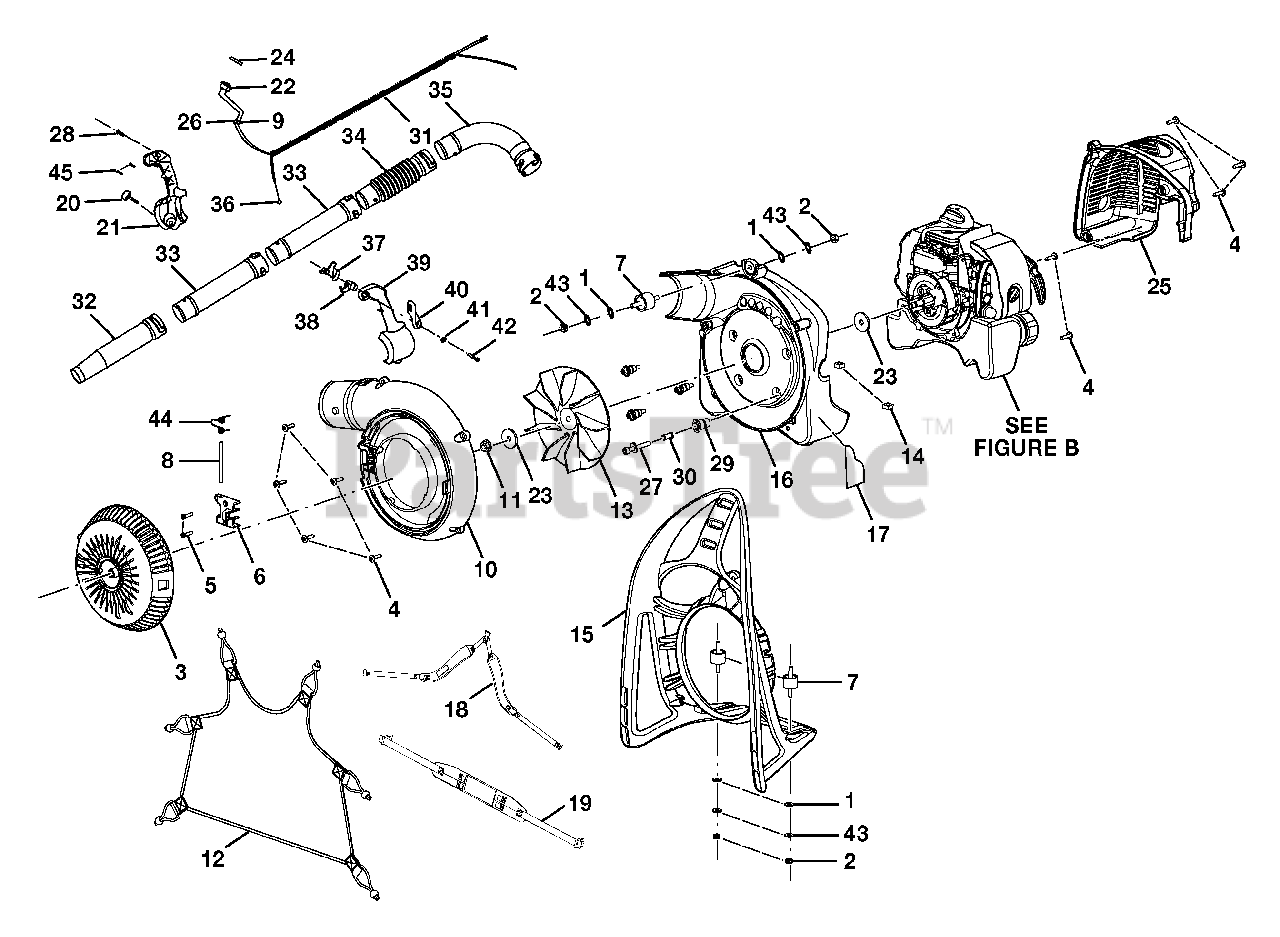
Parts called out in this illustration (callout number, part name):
4	SCREW (#10-14 X 7/8 in.)
5	SCREW (#8-14 x 16.3 mm)
6	VACUUM DOOR HINGE
7	RUBBER AV ISOLATOR
8	HINGE PIN
9	LEAD ASSEMBLY (BLACK)
10	OUTER VOLUTE HOUSING
11	RETAINING WASHER NUT
13	24.5 CC BLOWER FAN
14	SQUARE NUT
16	HOUSING INNER VOLUTE
17	WARNING LABEL
18	SHOULDER STRAPS
19	WAIST STRAP
21	HOUSING-RH
23	FAN SPACER WASHER
24	DUST COVER
25	ENGINE SHROUD HOUSING
26	LEAD ASSEMBLY (RED)
27	SCREW (M5 X 0.8 CAP HD.)
28	SCREW (#10-14 X 3/4 in.)
29	VIBRATION ISOLATOR
30	AV BUSHING SLEEVE
31	CORRUGATED TUBE
32	TUBE-LOWER BLOWER
33	TUBE-UPPER BLOWER
35	BLOWER ELBOW
36	CABLE ASSEMBLY
38	TRIGGER LOCK
39	HOUSING-LH
40	CRUISE LEVER
42	SCREW (#8-14 x 50 mm)
43	LOCK WASHER
45	SCREW (M4 X 1.75 X 16 PAN HD.)
